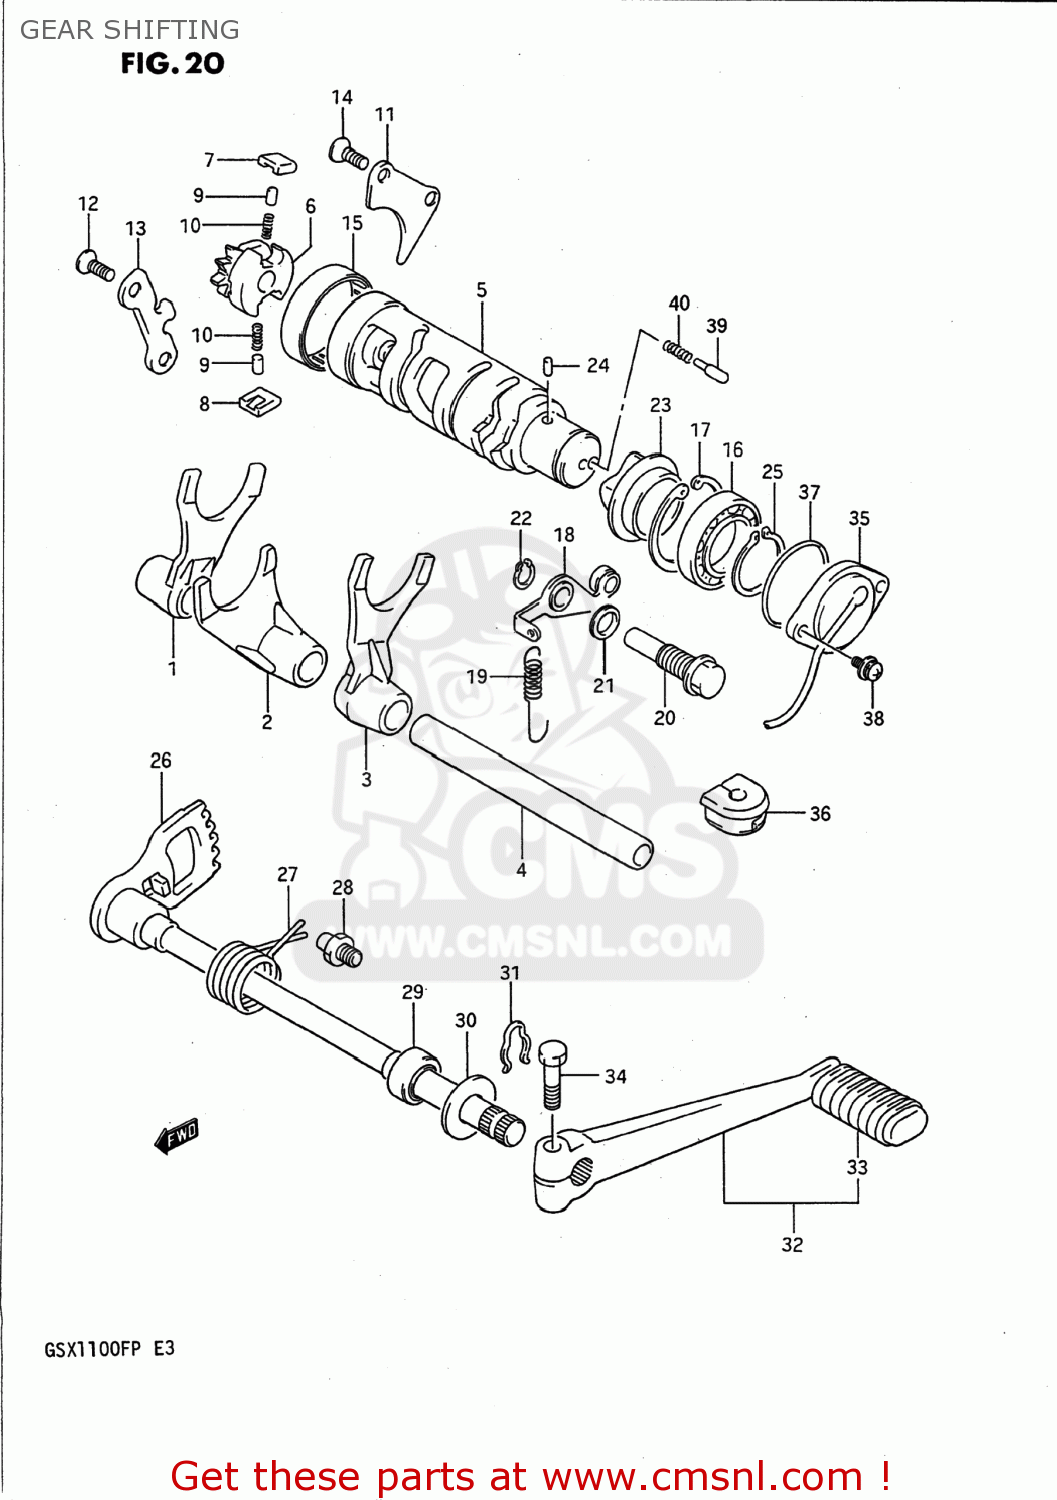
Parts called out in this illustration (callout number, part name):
1	FORK,GEAR SHIFT NO.1
2	FORK,GEAR SHIFT NO.2
3	FORK,GEAR SHIFT NO.3
4	SHAFT,GEAR SHIFT FORK(L:128)
5	CAM,GEAR SHIFT
6	GEAR,GEARSHIFT CAM DRIVE
7	PAWL,GEAR SHIFT NO.1
8	PAWL,GEAR SHIFT NO.2
9	PIN(5X8)
10	SPRING
11	LIFTER,GEAR SHIFT PAWL
12	SCREW
13	GUIDE,GEAR SHIFT CAM
14	SCREW
15	BEARING(43X49X12)
16	BALL BEARING
17	CIRCLIP
18	STOPPER,GEAR SHIFT CAM
19	SPRING
20	SHAFT,GEAR SHIFT CAM STOPPER
21	GASKET(10X14X3.6) (NAS)
22	CIRCLIP
23	PLATE,STOPPER
24	PIN 4X6
25	CIRCLIP
26	SHAFT,GEAR SHIFT
27	SPRING
28	STOPPER,GEAR SHIFT CAM
29	OIL SEAL
30	WASHER (12.5X27X1.6)
31	SPRING,RETAINER
32	LEVER ASSEMBLY,GEAR SHIFTING
33	RUBBER,PEDAL
34	BOLT
35	TERMINAL BASE ASSY,NEUTRAL
36	GROMMET,LEADWIRE
37	O RING(D:2.4,ID:36.5)
38	SCREW
39	PIN(5X15.5)
40	SPRING
